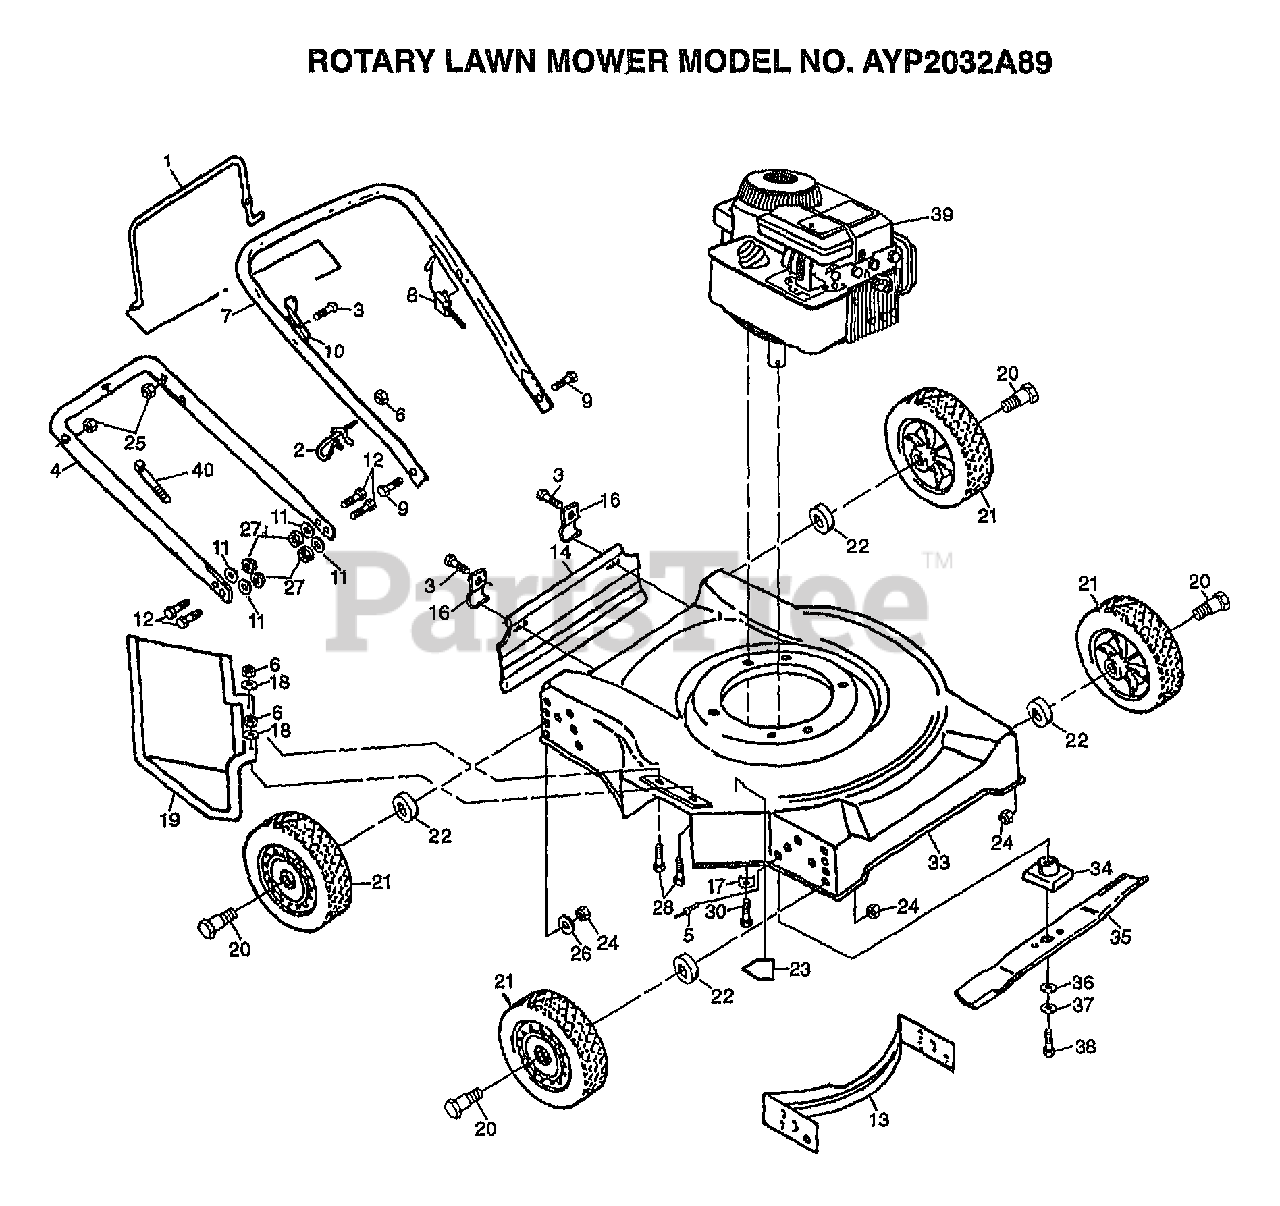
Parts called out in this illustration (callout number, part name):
1	CONTROL BAR PM
2	ROPE GUIDE
3	TAPPING SCREW
4	HANDLE LWR PM
5	BLIND RIVET
7	UPPER HANDLE
8	ENG ZONE CTRL CAB
9	BOLT 1/4-20-1 1/2
10	"BRKT,UPSTOP PM"
11	STEEL WASHER
14	SKIRT.REAR.20RD.
16	"BRKT,DEFL PM"
19	"GRD,DISCHARGE"
20	AXLE BOLT
21	WHEEL&TIRE
23	DECAL-DANGER PM
24	LOCKNUT PM
27	LOCKNUT
30	BOLT.ENG.3/8-16
33	KIT.HSG.20SD.PUSH
34	BLADE ADAPTOR
35	BLADE.20.MULCH.AY
36	"WASHER,HARDEN"
37	LOCKWASHER
38	SCREW
